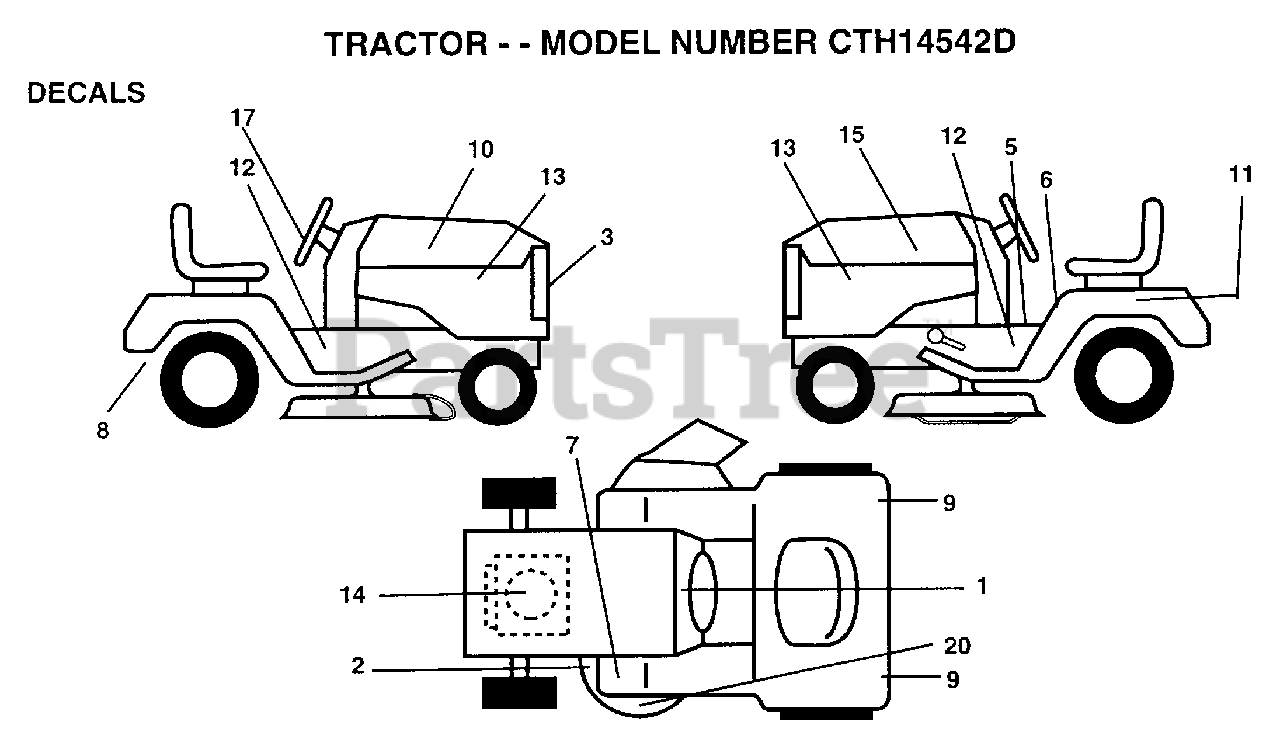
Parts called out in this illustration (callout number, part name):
1	"DECAL-INST,OPER"
2	DECAL
3	DECAL GRILLE
5	DECAL BRAK PARK
6	"DECAL DANGER,FEND"
8	DECAL DRAWBAR LH
9	REFLECTOR-TAIL YT
10	DECAL HOOD RH
11	DECAL.BATRY.3-3908
12	"DECAL CHASSIS 42"""
13	DECAL SIDE PANEL
14	DECAL, ENGINE
15	DECAL HOOD LH
17	DECAL INST STG WH
20	"DECAL,ENVIRO DECK"
